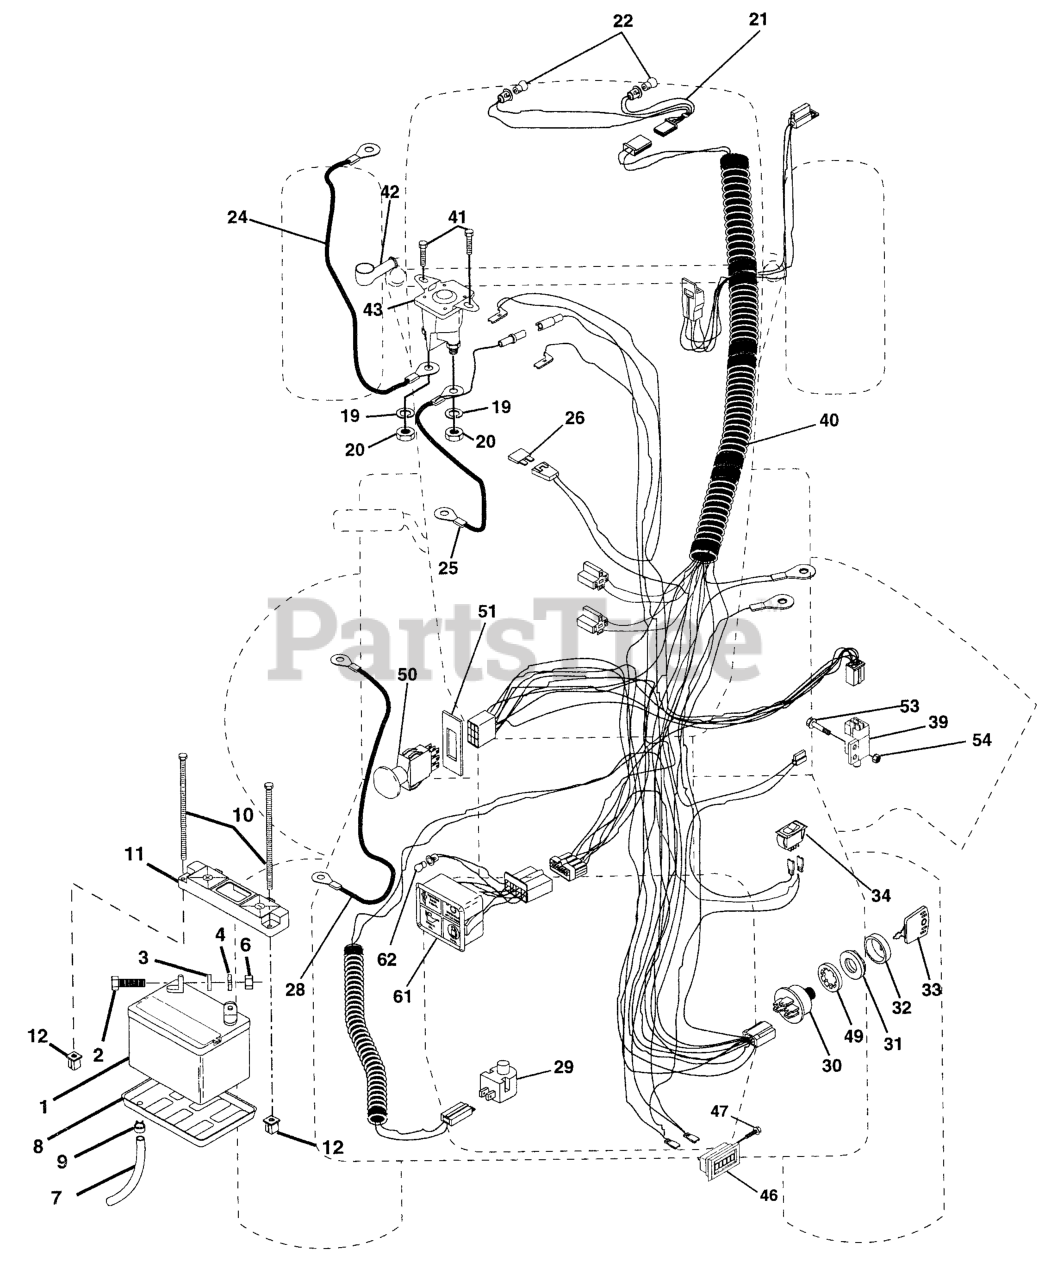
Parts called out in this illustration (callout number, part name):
1	BATTERY
2	BOLT.HEX.1/4.X.3/4.DICHROMATE
3	LOCKWASHER
4	WASHER
6	NUT
7	PLASTIC TUBE
8	BATTERY TRAY T
9	HOSE CLAMP T
10	BOLT 1/4-20 X 7.5
11	HOLDDOWN, BATTERY, DASH MOUNT
12	NUT, PUSH NYLON 1/4" BATTERY
19	LOCKWASHER
20	NUT
21	HARNESS LIGHT SOCKET
24	CABLE, STARTER
25	CABLE, BATTERY
28	CABLE, GROUND
29	RP.SWITCH.PLUNGER.NC.GRAY
30	IGNITION SWITCH
31	NUT, IGNITION
32	COVER SWITCH KEY
33	KEY MLD GEN DELTA
39	SWITCH INTERLOCKT
41	SCREW
42	TERMINAL COVER
43	SOLINOID
46	HOUR METER T
47	Screw #10-24 x 1/2
49	Washer, Lock Internal Tooth 5/8
50	SWITCH-PTO
51	FRAME RETAINING RING
53	SCREW **
54	Nut Keps #10-32
61	LIGHT PACKAGE
62	BULB LIGHT T
